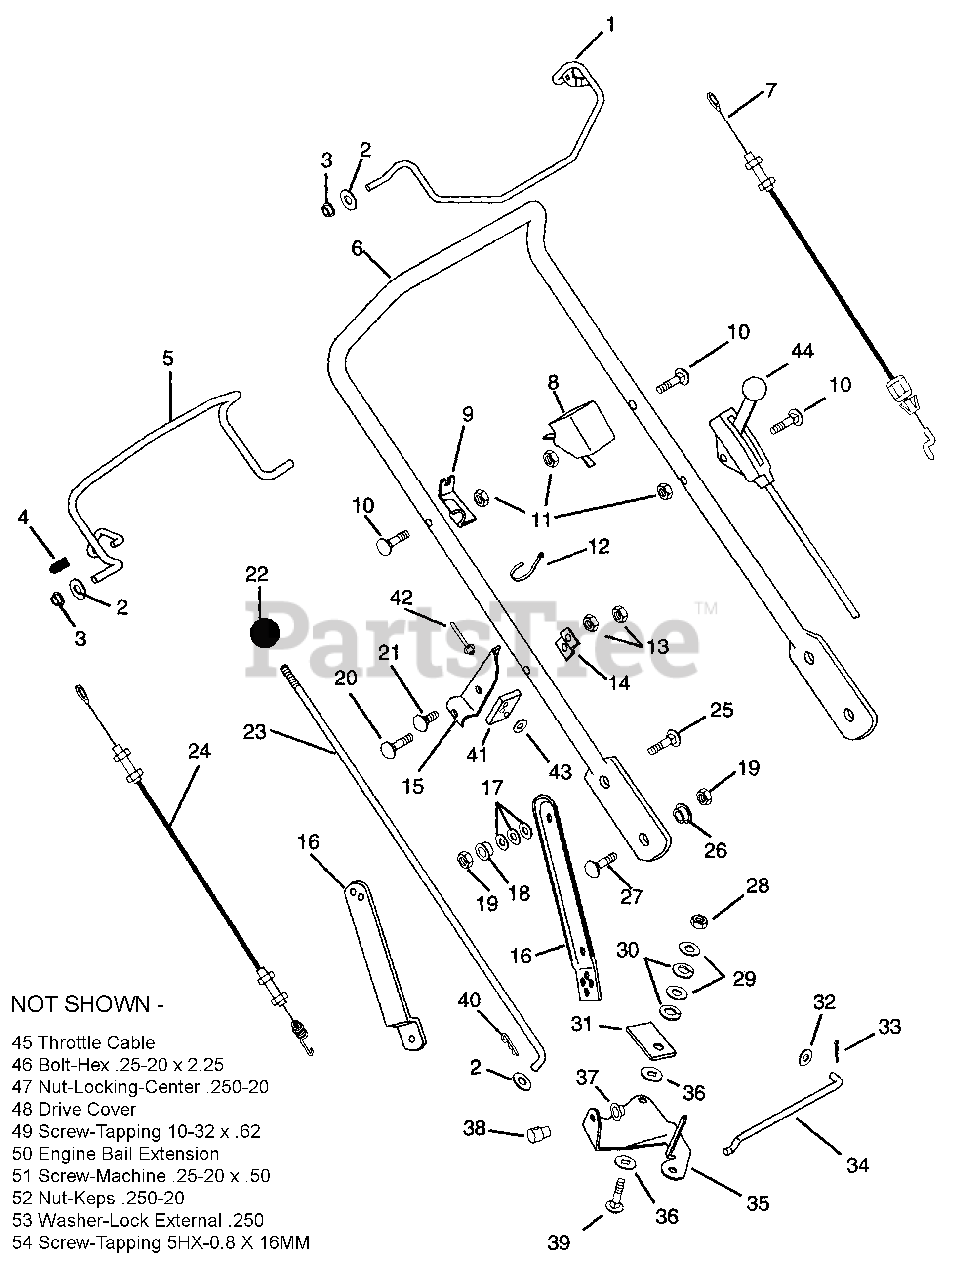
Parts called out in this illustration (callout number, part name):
1	ENGINE BAIL TEC. 2 CYCLE
1	ENGINE BAIL
2	WSHR-FL-STL.344X.688X.065PL
3	BSHG-FLG .325X.444X.440X.560
4	CAP, VINYL, .25 ID
5	TRACTION BAIL
6	HANDLEBAR PUSH
6	HANDLEBAR SELF-PROPELLED
7	ENGINE CONTROL CABLE
7	ENGINE CABLE KAWASAKI
7	ENGINE CABLE
8	SWITCH-CABLE ANCHOR
9	CABLE ANCHOR
9	CABLE ANCHOR-LH
10	BLT-RDHDSQNK .25-20X1.25 XLGPL
11	NUT-KEPS .250-20
12	CABLE TIE LG 5-1/2
13	NUT-LK-CTR .250-20 PL
14	BRACE-SPEED CONTROL
15	BRACKET-SPEED CONTROL
16	LINK,HANDLE BAR ADJUST LH
16	LINK,HANDLE BAR ADJ RH
16	HANDLEBAR BRACKET
17	WASHER,BELLEVILLE SPRING
18	BSHG-FLG .325X.500X.513X.875
19	NUT-LK-TOP .312-18 GR C PL
20	BLT-RDHDSQNK .25-20X1.38SHT PL
21	@BLT-RHDSSQNK .25-20X.38 G2YZ
22	KNOB, BALL 5/16-18 X 1.5
23	ROD-SPEED CONTROL
24	TRACTION CABLE
25	BLT-RDHDSQNK .31-18X1.12 GR5PL
26	BSHG, FLG .325X.499X.26X.88
27	BLT-RDHDSQNK.31-18X.88 GR5YWZC
28	NUT-LK-CTR .375-16 GR A PL
29	WSHR-FL-STL.406X.812X.065PL
30	WSHR-LK .375X.115 HVY PL
31	PRESSURE FLANGE
32	WSHR-FL-STL.281X.62X.065 PL
33	PIN-COTR .06X.50
34	SHIFT LINK
35	BELL CRANK - SPEED CONTROL
36	FRICTION WASHER
37	CAP, 3/8 ROD YWZC
39	BLT-RDHDSQNK .38-16X1.50 PL
40	PIN-HAIR INT .08X.18X1.18
41	SUPPORT PAD
42	RVT .187X.450 DOME AL BLACK
43	WSHR-FL-STL .194X.492X.047 PL
44	SHARE, 125 CM
44	THROTTLE CABLE
45	THROTTLE CABLE
46	BLT-HEX .25-20X2.25
48	DRIVE COVER
49	SCR-TAP 10-32X.62 HWH PL T
50	ENGINE BAIL EXTENSION
51	SCR-MCH .25-20X.50 SLRH
52	NUT-KEPS .250-20
53	WSHR-LK-EXT. 250 ID
54	TAPTITE M5-0.8X16MM H-FL-PL
